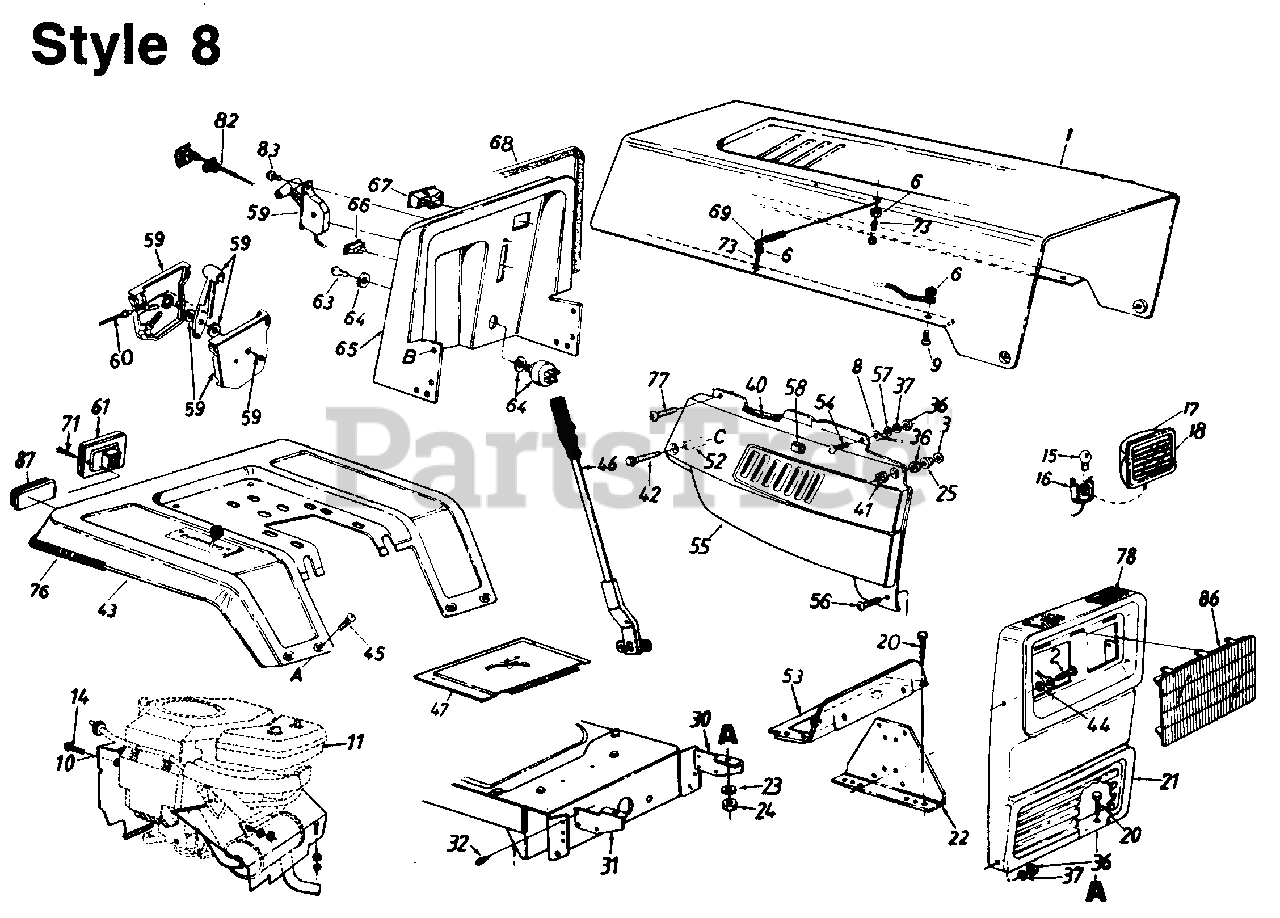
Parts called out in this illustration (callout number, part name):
1	Hood
3	Washer .39" I.D. x .62"
6	Hex Sems Nut #10-24 Thd.
8	Hood Stop
9	Truss Hd. Scr. #10-24 x 1/2"
10	Baffle w/Trim Strip
11	Engine
14	Hex Tap Scr. 1/4-20 x .5" Lg.
15	Bulb
16	Twist Lock-Bulb Socket
17	Headlight Housing
18	Lens
20	Hex Bolt 5/16-18 x .75" Lg.
23	L-Wash. 5/16" I.D.
24	Hex Nut 5/16-18 Thd.
25	Shld. Spacer
30	Grille Mount Brkt.-L.H.
36	Hex Nut 1/4-20 Thd.
37	L-Wash. 1/4" I.D.
40	Trim Strip-12" Lg.
41	Acron Nut 1/4-20 Thd.
42	Hex TT-Tap Scr. 1/4-20 x 1.75" Lg.
43	Rear Fender
45	Carriage Bolt 1/4-20 x .50"
46	Lift Handle
47	Transmission Panel
52	Spacer 1.30" Lg.
53	Support Brkt.
54	Truss Hd. Scr. 1/4-20 x .75"
57	Fl-Wash. .281" I.D. x .73" O.D.
58	Mounting Clamp
59	Throttle Control Box Ass'y.
60	Throttle Control Wire
61	Taillight
63	Ignition Key
64	Ignition Switch
67	Ammeter
68	Trim Strip-31"
69	Hood Spring
71	Truss Hd. AB Tap Scr. #6 x .62" Lg.
73	Hex Scr. #10-24 x 1.0" Lg.
76	Trim Strip-81"
77	Hex Wash. Hd. Tap Scr. 1/4 x .75" Lg.
78	Foam Strip 3/8 x 1-1/8" x 11/2 Lg.
82	Choke Control 46" Lg.
83	Truss Mach. AB-Tap Scr. #10 x .5" Lg.
86	Headlight Bezel
87	Reflector
